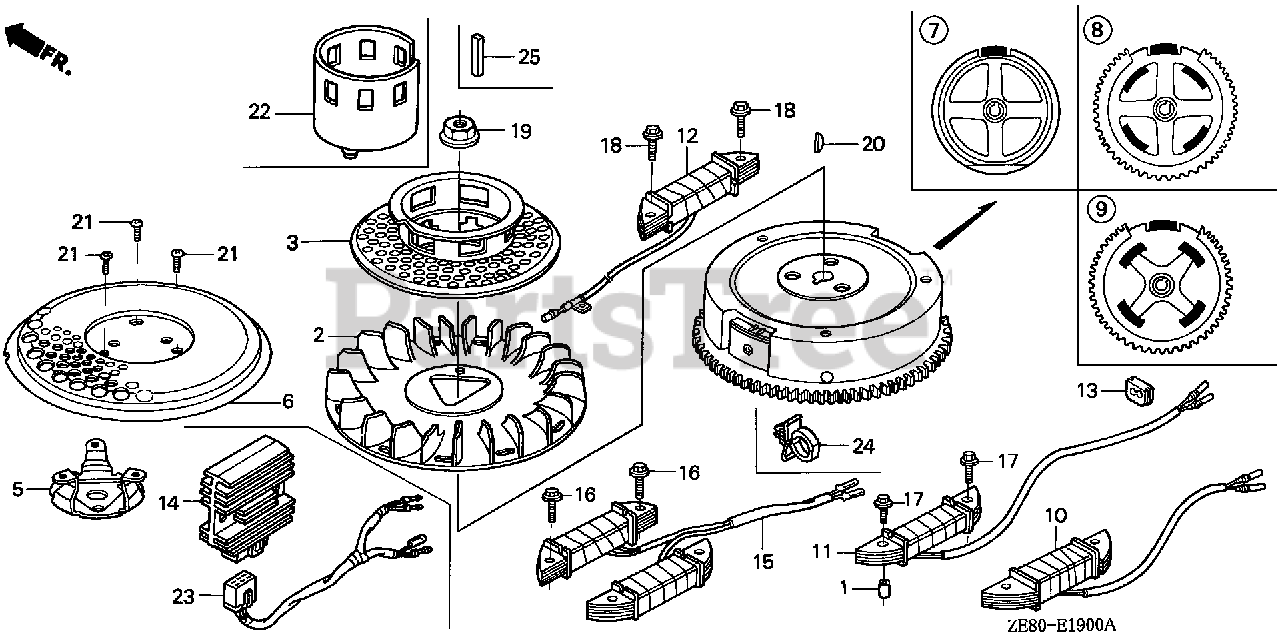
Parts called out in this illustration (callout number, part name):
1	COLLAR, EXTENSION
2	FAN, COOLING
3	PULLEY, STARTER (NOT AVAILABLE)
8	FLYWHEEL (SEL-4POLE)
10	COIL ASSY., CHARGE (2A-3A)
13	GROMMET, WIRE
17	BOLT, FLANGE (6X28) (CT200)
17	BOLT, FLANGE (6X25) (CT200)
19	NUT, SPECIAL (16MM)
20	KEY, SPECIAL WOODRUFF (25X18)
